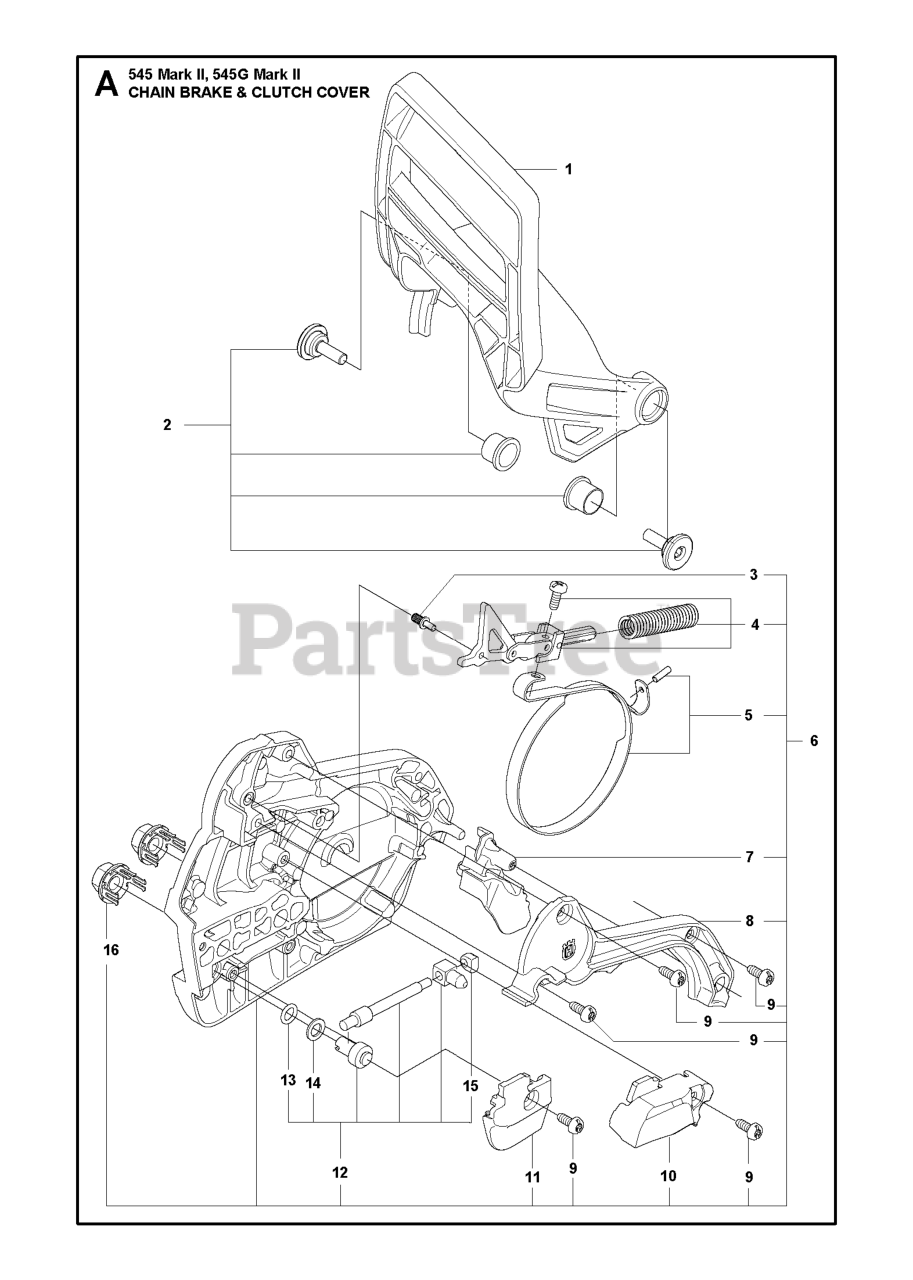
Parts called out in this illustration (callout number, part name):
1	HAND GUARD PRODUCTION TOOL - S
4	KNEE JOINT ASSY KIT 50CC MARK
5	BRAKE BAND
6	CLUTCH COVER ASSY 50CC AND 60
10	CHAIN GUIDE UPPER
11	CHAIN GUIDE
12	CHAIN TENSIONER KIT
16	NUT RETAINER ASSY
